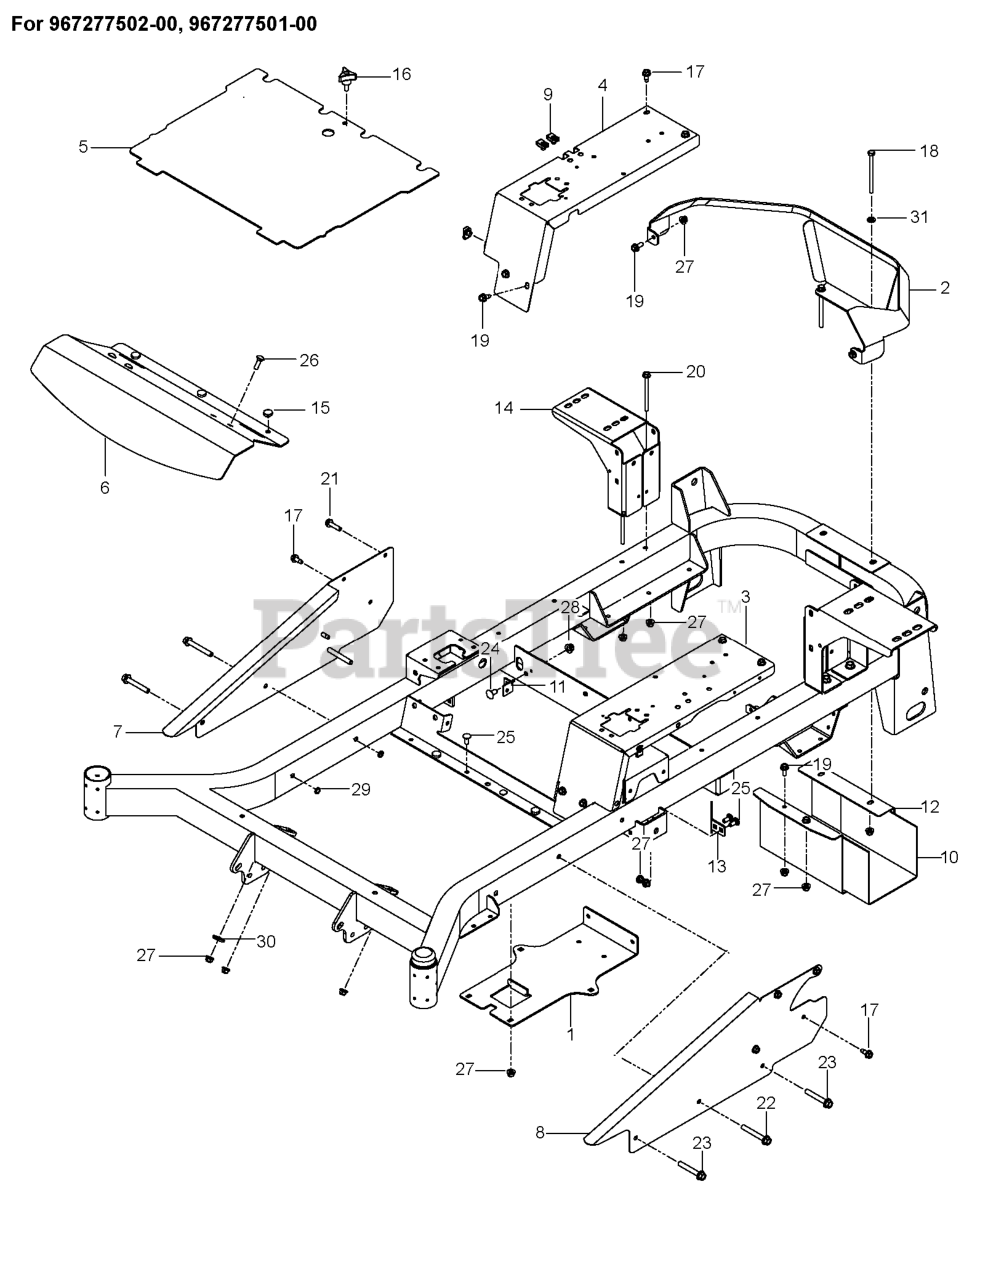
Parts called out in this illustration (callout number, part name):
1	PLATE, BATTERY, BLACK
2	GUARD, REAR MZ, GRAY
3	PANEL.FILLER.LT.ORANGE
4	PANEL.FILLER.RT.ORANGE
5	PLATE, FLOOR W/DECALS
6	PLATE, FOOTREST
7	SIDE.RT.ORANGE
8	SIDE.LT.ORANGE
9	U-CLIP 5/16-18 NUT RETAINER
10	HEAT SHIELD
11	BRACKET.DAMPENER.BLACK
12	SHIELD.MUFFLER.BLACK
13	STOP, DECK, EZ+
14	MOUNT, TANK, ZT BLK
15	GROMMET, BUMPER
16	KNOB W/STUD
17	BOLT 5/16-18 X 3/4
18	HCS 5/16C X 4
19	HHFS 5/16-18 X 3/4
20	HHFS 5/16-18 X 3 3/4
21	HHFS 5/16-18 X 1.25 TPBLT GD 5
22	HHFS 3/8-16 X 2 3/4
23	HHFS 3/8-16 X 2.5 GR 5 ZD
24	RHSNB 3/8-16 X 3/4 GR 5 BLK ZN
25	BOLT 5/16C X 3/4" CARRIAGE
26	RHSNB 5/16C X 1
27	5/16-18 NYLOC FLANGE NUT
28	NUT 3/8-16 HEX FLG NYLOC ZD
29	NUT HEX 3/8-16 NYLON, THIN
30	WASHER 1/2" FLAT
31	FLAT WASHER 5/16 SAE
